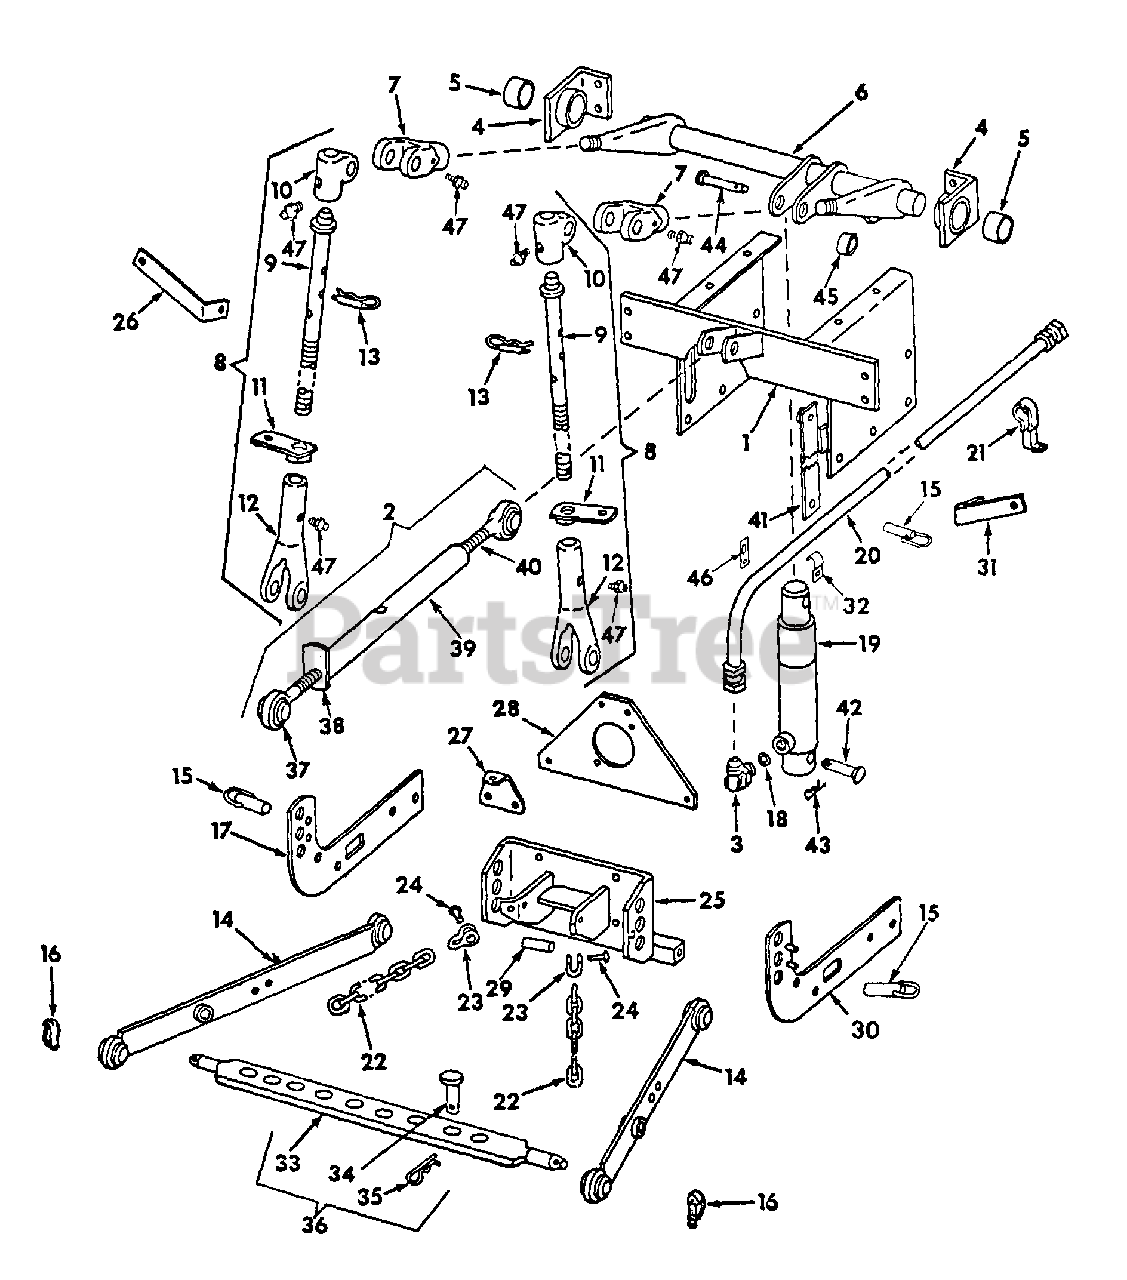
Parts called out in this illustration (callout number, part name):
1	SUPPORT ASSY, ROCKSHAFT
2	LINK ASSY, UPPER
3	ELBOW, 9/16-18 37 DEG HYD FLARED TUBE ADJ STR THD 90 DEG
4	BEARING ASSY, ROCKSHAFT
6	ROCKSHAFT ASSY.
7	SWIVEL, ROCKSHAFT ARM
8	LINK ASSY, LIFT
9	SCREW ASSY, LEVELING
10	SWIVEL, LIFT LINK
11	LOCK ASSY, LINK
12	HOUSING, LEVELING SCREW
13	PIN ASSY, QUICK ATTACHABLE COT.
14	LINK ASSY, LOWER
15	PIN ASSY, LOWER LINK
16	PIN ASSY, LOWER LINK DRAWBAR
17	BAR ASSY, LOWER LINK MTG LH
18	O-RING, 3/8 OD TUBE
19	CYLINDER ASSY, HYD 1-3/4 X 5 SINGLE ACTING
20	HOSE ASSY, HYDRAULIC
22	CHAIN, LIMITER
23	SHACKLE, LIMITER CHAIN
24	PIN, CHAIN SHACKLE
25	PLATE ASSY, LINK MOUNTING
26	BRACE, REAR FRAM SHIELD LH
26	BRACE, REAR FRAM SHIELD IH
27	SUPPORT ASSY, UPPER SHEILD
28	SUPPORT ASSY, SHIELD
29	SPACER, CHAIN ANCHOR
30	BAR ASSY, LOWER LINK MTG RH
31	BRACE, REAR FRAME SHIELD RH
31	BRACE, REAR FRAME, SHIELD RH
32	CLAMP, HYDRAULIC HOSE
34	PIN, DRAWBAR LOCKOUT
35	PIN, QUICK ATTACHABLE COT.
36	PARTS ACCESSORY, CROSS DRAWBAR
37	END, REPAIR RH
39	LOCK, UPPER LINK
40	END, REPAIR LH
41	LOCK ASSY, HITCH
42	PIN, CYLINDER PIVOT
43	PIN, QUICK ATTACHABLE COT.
44	PIN, 5/8 X 4 STD-HD
45	SPACER, HITCH LOCK
46	SUPPORT, HOSE CLAMP
47	FITTING, 1/8-27 PTF STR LUBRICATION
